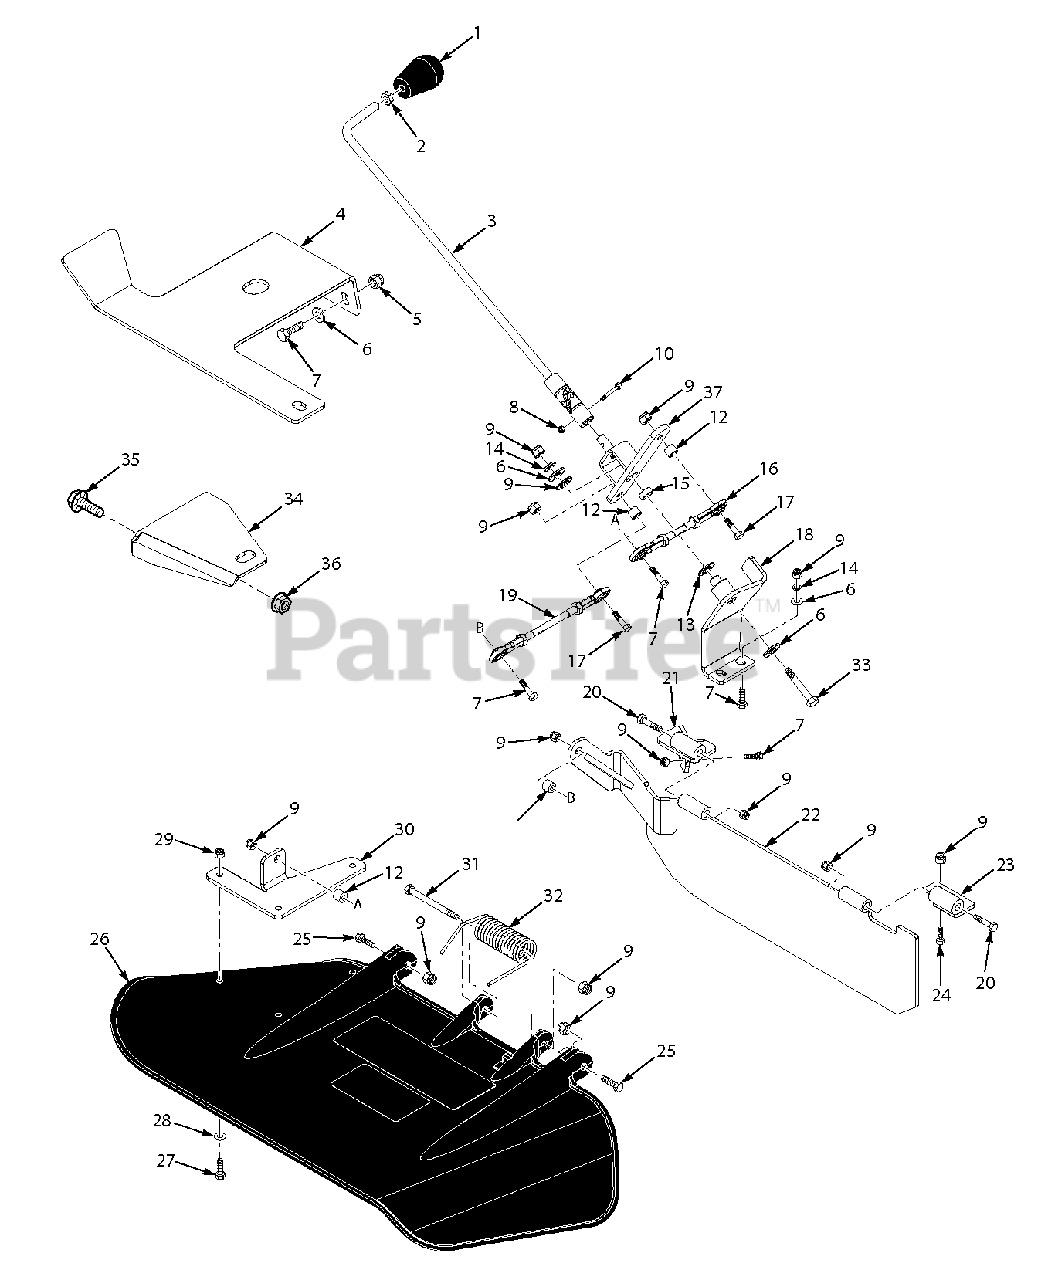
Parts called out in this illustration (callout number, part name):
1	Knob, Soft Touch
2	Nut, 3/8-16 UNC Jam
3	Lever Weldment, OCDC
4	Bracket, Lever Support
5	Nut, Serrated Flange 5/16-18
6	Flatwasher, 5/16-.375 x .875 x .083
7	Bolt, Hex Head 5/16-18 x 1"
8	Nut, Elastic Stop #8-32
9	Nut, Elastic Stop 5/16-18
10	Capscrew, Socket Head #8-32 x 1-1/4"
11	Pivot Arm Weldment
12	Sleeve
13	Washer, Thrust 1/2" ID
14	Lockwasher, 5/16" Spring
15	Bearing
16	Linkage Assembly
17	Bolt, Hex Head 5/16-18 x 1-1/2"
18	Pivot Weldment
19	Linkage Assembly
20	Bolt, Hex Head 5/16-18 x 3-1/2"
21	Hinge Weldment, Rear
22	Block-Off Plate Weldment
22	Hinge Weldment, Front
23	Bolt, Hex Head 5/16-18 x 3/4"
24	Bolt, Hex Head 5/16-18 x 1-3/4"
25	Discharge Chute Assy.,
26	Discharge Chute Assy.,
27	Bolt, Hex Head 1/4-20 x 3/4"
28	Flatwasher, 1/4-.312 x .750 x .065
29	Nut, Elastic Stop 1/4-20
30	Plate, Discharge Chute
31	Bolt, Hex Head 5/16-18 x 4-3/4"
32	Spring, Discharge Chute
33	Bolt, Hex Head 5/16-18 x 2"
34	Guide Bracket, OCDC Lever - STT
35	Bolt, 5/16-18 x 3/4" Serrated Flange
36	Nut, 5/16-18 Serrated Flange
37	Pivot Arm Weldment
